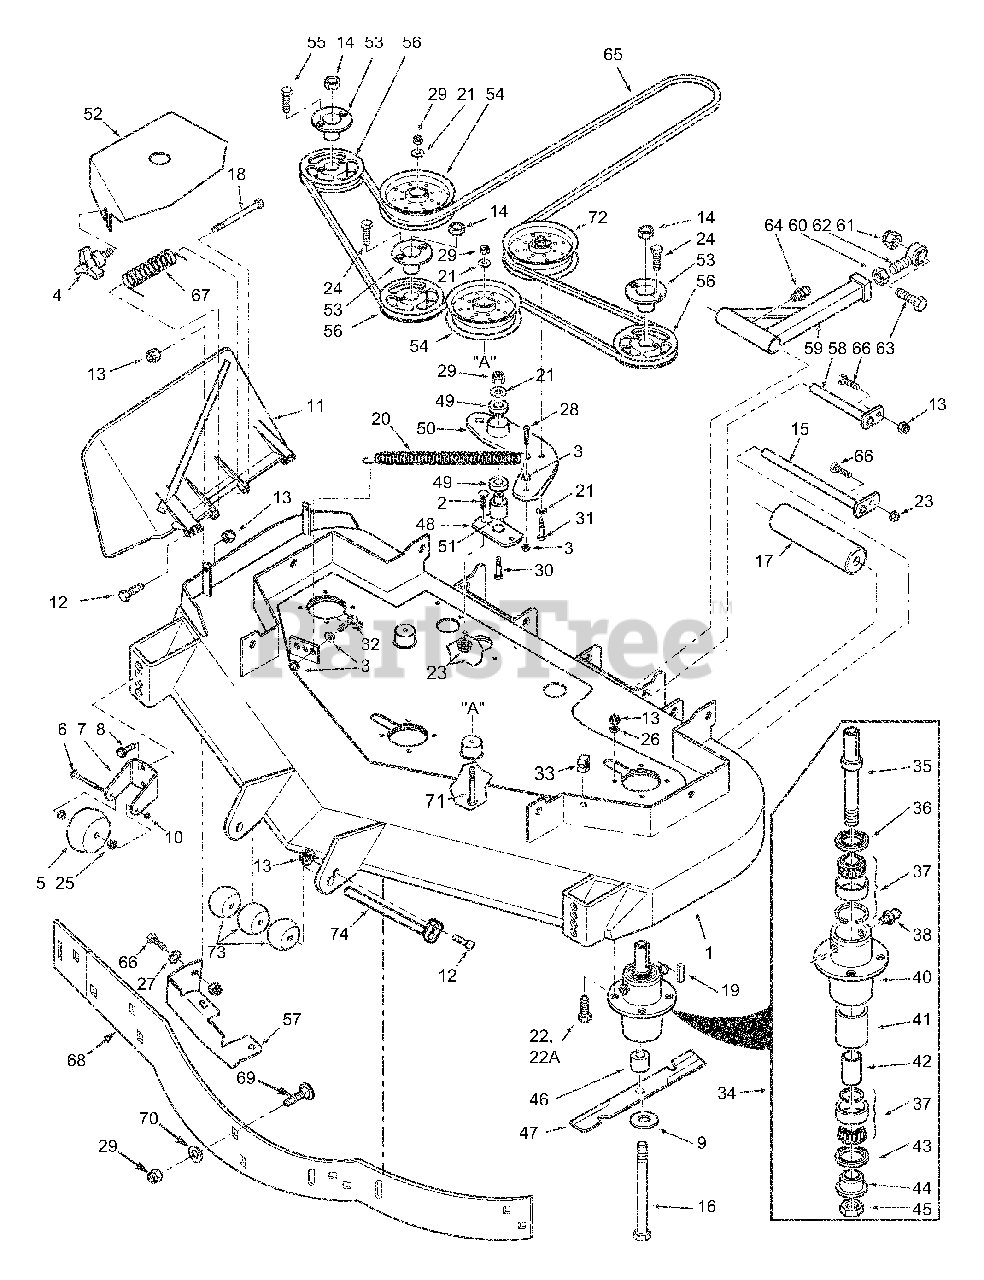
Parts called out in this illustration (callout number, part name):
1	Cutter Deck Advantage
2	Bolt, Carr. 5/16-18 x 1"
3	Nut, 3/8-16 Serrated Flange
4	Wing Nut, 3/8-16
5	Anti-Scalp Wheel
6	Bolt, Carriage 3/8-16 x 4"
7	Bracket, Anti-Scalp Wheel
8	Bolt, Serrated Flange 3/8-16 x 1"
9	Flatwasher, 5/8" Hardened
10	Locknut, 3/8-16 Center Lock
11	Discharge Chute
12	Bolt, Hex Head 5/16-18 x 1-1/2", Rear
13	Nut, Elastic Stop 5/16-18
14	Nut, 5/8-11 UNC
15	Shaft, Roller
16	Bolt, Hex Head 5/8-11 x 9-1/2"
17	Roller, Rear
18	Bolt, Hex Head 5/16-18 x 4-3/4"
19	Key, 1/4 x 1/4 x 2"
20	Spring, Idler
21	Flatwasher, 3/8" - .938 x .391 x .105
22	Bolt, Hex Head 5/16-18 x 1-1/2"
22A	Bolt, Hex Head 5/16-18 x 1-3/4"
23	Nut, Serrated Flange 5/16-18
24	Bolt, Hex Head 1/2-20 x 1"
25	Bushing, .376 ID Oilite
26	Lockwasher 5/16"
27	Flatwasher 5/16"
28	Bolt, 3/8-16 x 1-1/2" Grade 8
29	Nut, Elastic Stop 3/8-16
30	Bolt, Hex Head 3/8-16 x 2-1/2"
31	Bolt, Hex Head 3/8-16 x 3"
32	Bolt, Hex Head 3/8-16 x 1-1/2 Grade 8
33	U-Nut, 3/8-16
34	Spindle Assembly
35	Shaft, Spindle
36	Seal Upper
37	Bearing Assembly
38	Grease Fitting
40	Housing, Spindle
41	Spacer, Outside
42	Spacer, Inside
43	Seal, Lower
44	Bushing, Bottom
45	Nut, Special 1-1/16 - 18
46	Spacer, Spindle
47	Cutter Blade 21"
48	Pivot, Idler Base
49	Bearing
50	Idler Arm Assy.
51	Idler Pivot, Short
52	Belt Cover (61A)
53	Hub, Tapered 1-1/8" Bore
54	Pulley, Idler 5.0"
55	Bolt, Hex Head 1/4-20 x 1"
56	Pulley, 5.95 Dia. Tapered Bore
57	Turbo Baffle, Bolt On
58	Push Arm Shaft
59	Push Arm
60	Nut, 5/8-18 UNF
61	Nut, Elastic Stop 5/8-11
62	Rod End, 5/8 Male RH Thread
63	Bolt, Hex Head 5/8-11 x 4-1/2"
64	Grease Fitting, 90 Degree
65	Belt, Cutter Deck Drive (61A)
66	Bolt, Hex Head 5/16-18 x 1"
67	Spring, Discharge Chute
68	Baffle Weldment, 61A
69	Bolt, Carriage 3/8-16 x 1"
70	Flatwasher, 3/8-.391 x .938 x .105
71	Bolt, Hex Head 3/8-16 x 3-3/4"
72	Pulley, Idler 5.0" OD
73	Wheel, Anti Scalp
74	Roller Shaft
